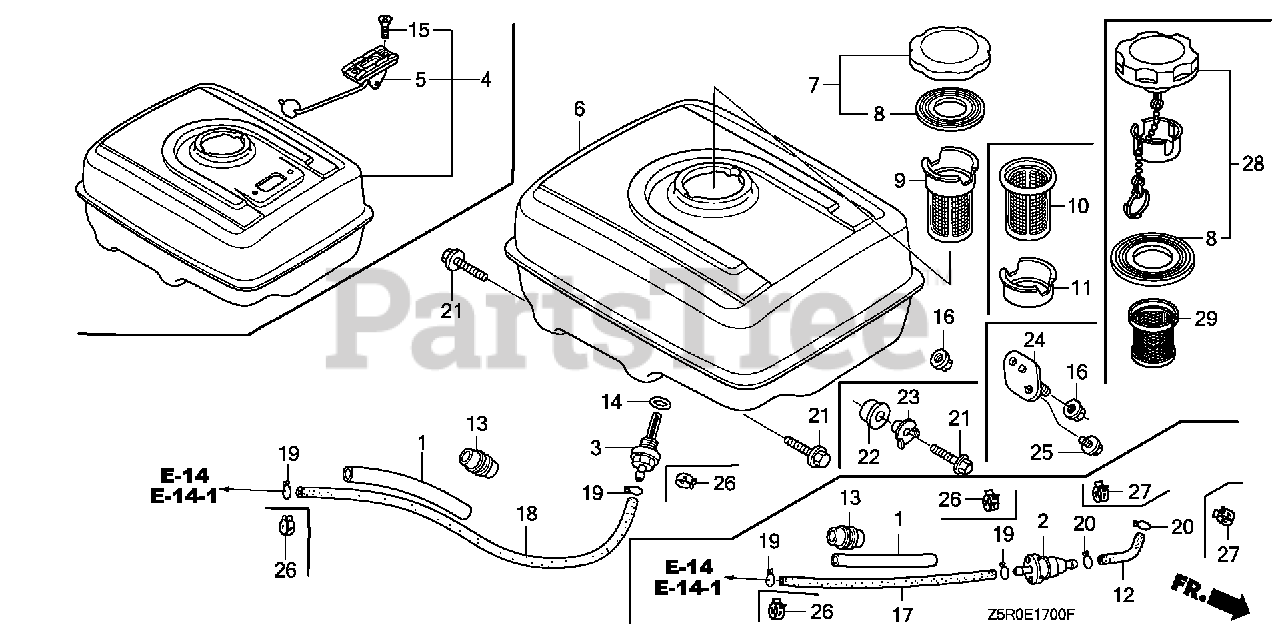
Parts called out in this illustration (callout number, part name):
1	RUBBER, SUPPORTER (107MM)
3	JOINT, FUEL TANK
6	TANK, FUEL *NH1* (BLACK)
6	TANK, FUEL *NH31* (MCKINLEY WHITE)
8	GASKET, FUEL FILLER CAP
14	O-RING (14MM) (ARAI) Use up to Engine SN 2949254.
14	O-RING (14MM) (NOK)
16	NUT, FLANGE (8MM)
18	TUBE, FUEL (4.5X235) (FKM)
21	BOLT, FLANGE (8X25)
26	CLIP, TUBE (D8)
28	CAP, FUEL FILLER
29	FILTER, FUEL (FROM 1204807)
